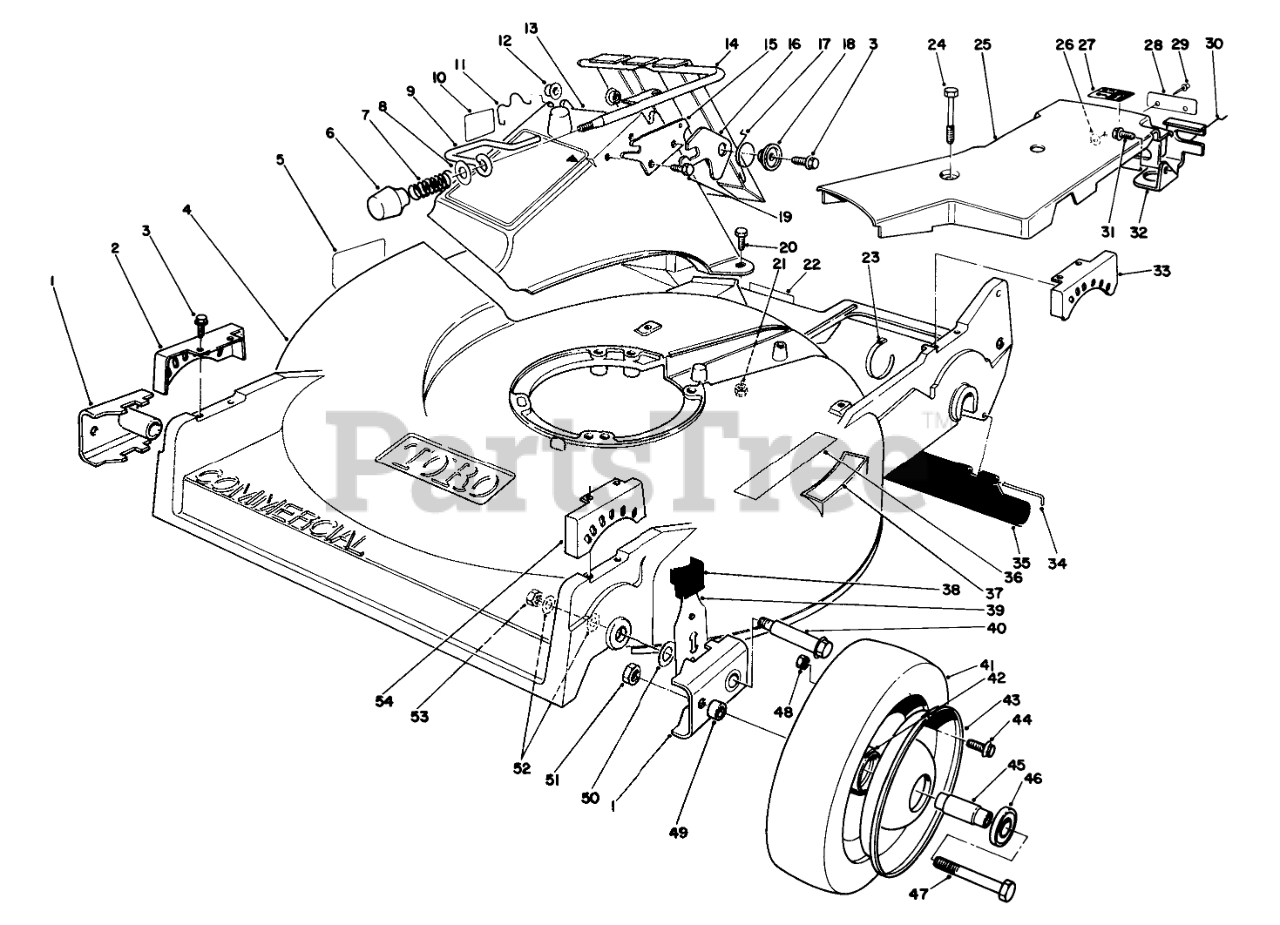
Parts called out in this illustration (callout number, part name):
1	ARM-PIVOT, FRONT
2	QUADRANT-FRONT, RH
3	SCREW-HWHTF
4	Housing-Commercial (Incl. Ref. #5 & 35)
5	Decal Danger
7	COMPRESSION SPRING
8	WASHER-FLAT
9	DOOR LATCH
10	DECAL - DANGER
11	DOOR RETAINER
12	BUSHING-NYLON
13	DISCHARGE CHUTE B
14	DOOR & HANDLE WA
15	DOOR LATCH PLATE
16	SAFETY LATCH
17	TORSION SPRING
18	DOOR SPACER
19	SCREW-HWH
20	SCREW-HH
21	NUT-LOCK, NI
22	Decal
23	TIE-CABLE
24	SCREW-HHFTF
25	Belt Cover Assembly (Incl. Ref. #26, 28-29)
26	WASHER-PLAIN
27	Label-Grease
28	Name Plate-Ground Speed
30	RETAINER-CABLE
31	SCREW-HWHTF
32	Bracket-Traction Adj.
33	QUADRANT-REAR, LH
34	ROD-SHIELD
35	SHIELD-TRAILING
36	Decal-Danger
37	DECAL - STEP PAD INT'L
38	KNOB-ARM
39	Spring Arm Assembly Front
40	WHEEL BOLT
42	HUB-BEARING
43	Wheel-Half
44	SCREW-HHF
45	SPACER-BEARING
46	BEARING-WHEEL
47	SCREW-HH
48	NUT-LOCK, NI
49	SPACER-WHEEL
50	WASHER-THRUST
51	NUT-LOCK, CONE
52	WASHER
53	Nut
54	QUADRANT-FRONT, LH
